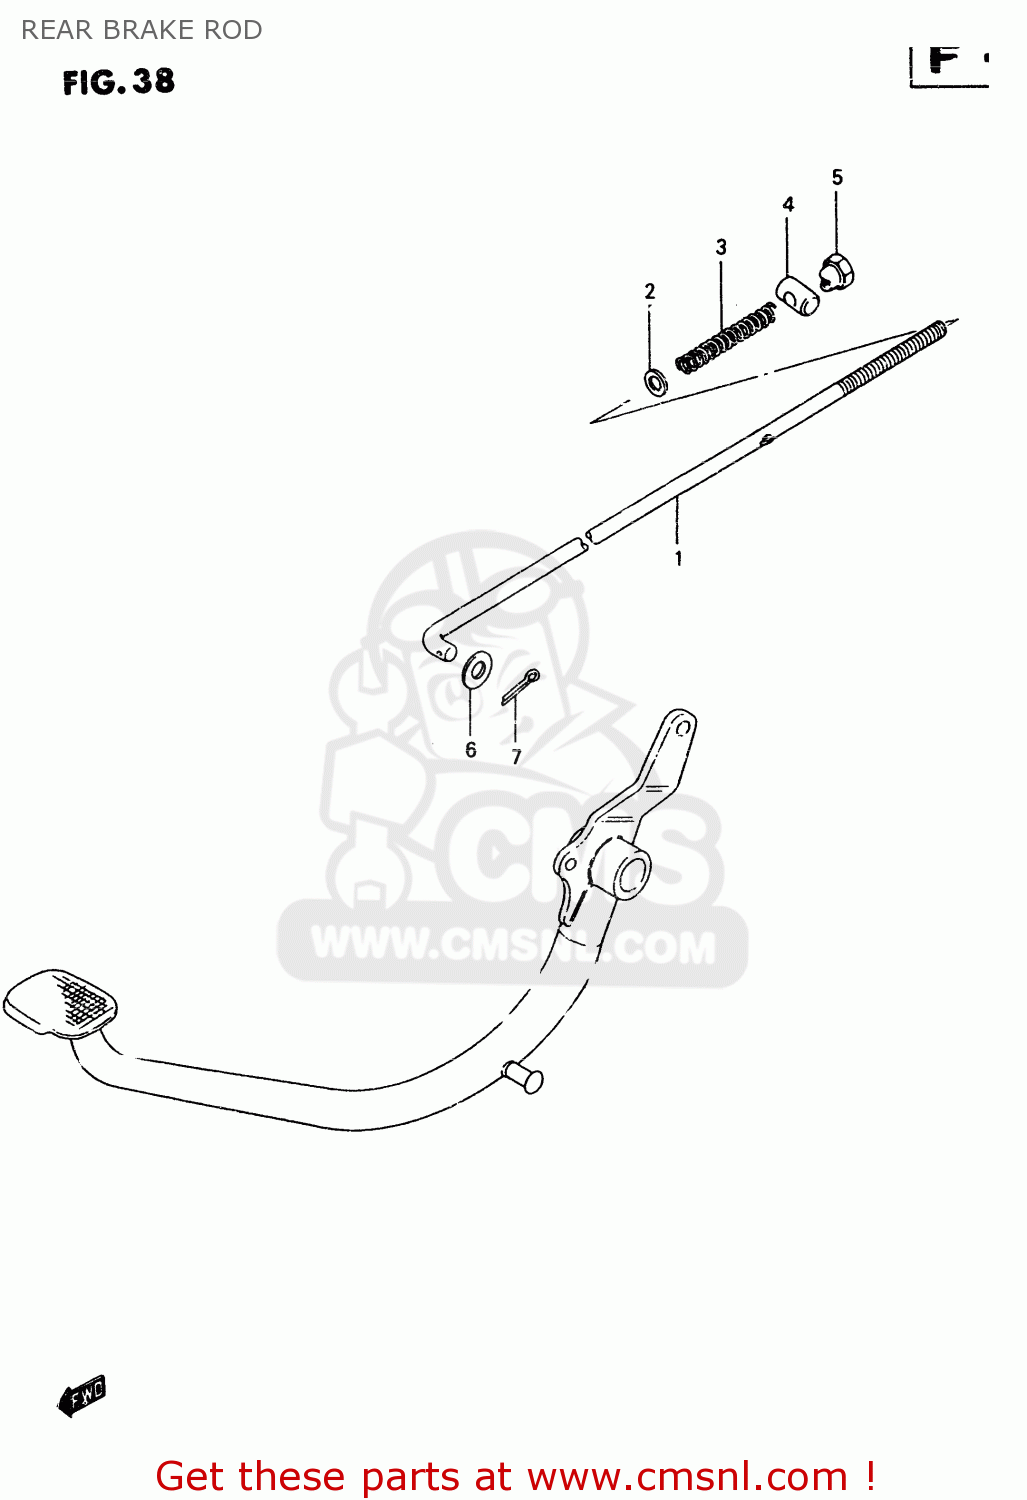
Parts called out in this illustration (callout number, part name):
1	ROD ASSY,RR BRAKE
2	WASHER
3	SPRING
4	PIN(13X18)
5	NUT
6	WASHER
7	PIN 20X20
